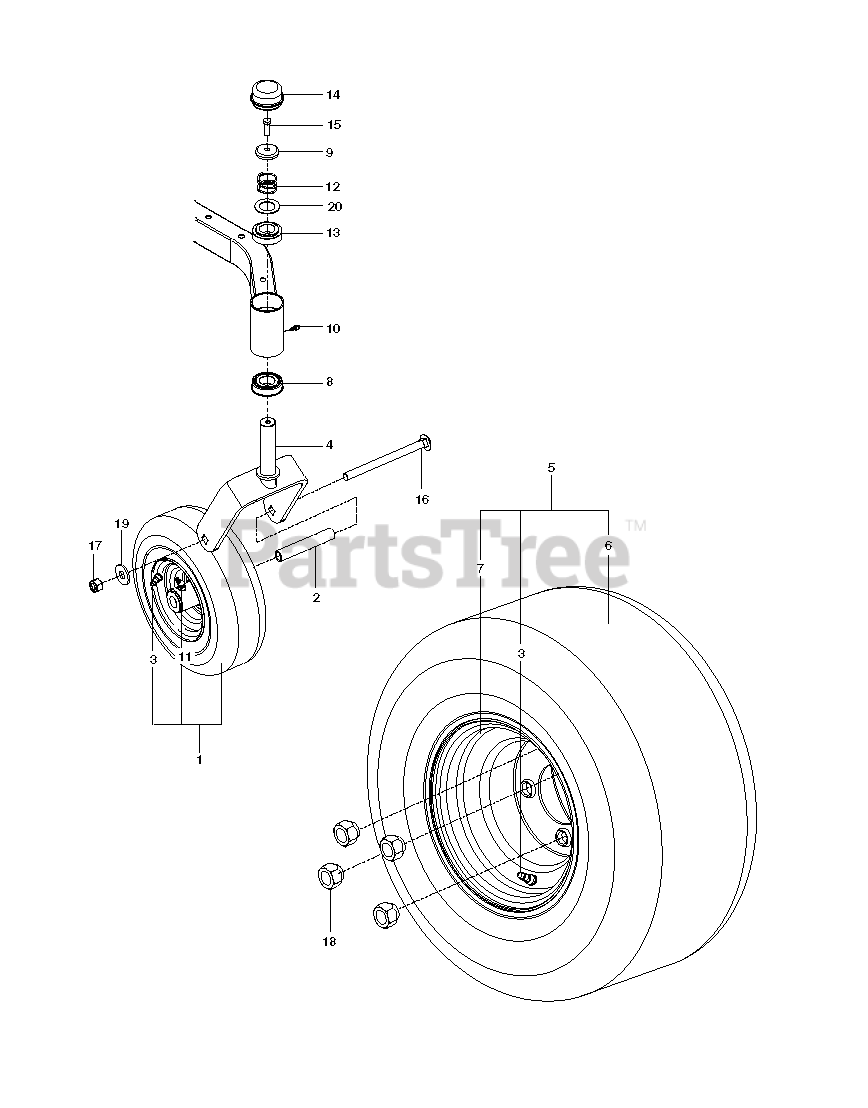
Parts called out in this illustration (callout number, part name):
2	SPACER, PIVOT
3	VALVE STEM TR-412
4	YOKE, CASTER, BLUE
7	RIM 8 X 7 , W 8" OFFSET
8	BEARING FLANGED
9	CASTER.PLUG
10	ZERK, 3/16, DRIVE IN
11	ZERK
12	SPRING, CASTER
13	BUSHING, CASTER
14	GREASE CAP
15	5/16-18X1 HHB G5W/NY
16	RHSNB 1/2-13 X 7.5
17	NUT 1/2-13 HEX CNTRLK GR 5 ZD
18	LUG NUT 1/2F
19	WASH USS FLAT 1/2
20	WASHER, 1.025 ID X 1.64
